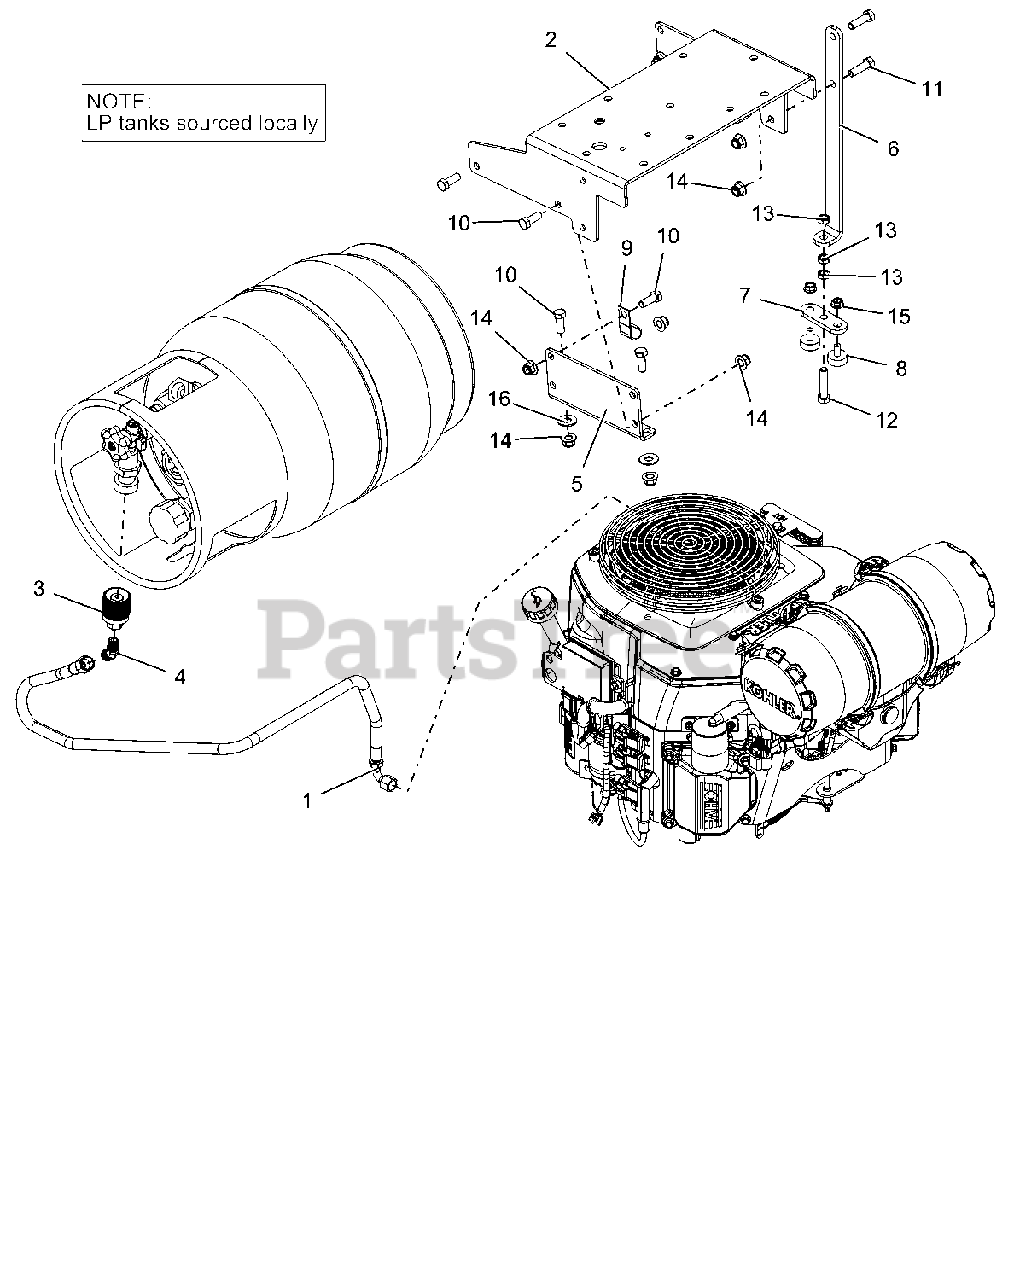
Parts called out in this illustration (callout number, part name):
1	HOSE, LPG SS25UL 6-4-6-30.00
2	SUPPORT, TANK
3	FTG, LPG TANK COUPLER -LH THRD
4	FTG, 45° 1/4-NPTF 9/16-18 45 FLG
5	MOUNT, TANK
6	STAND, TANK SIDE
7	BAR, FOOT
8	BUMPER, RUBBER
9	P-CLIP, .500 INSULATED
10	BLT-HEX .38-16X1.00 GR5 YWZC
11	BLT-HEX .38-16X1.25 GR5 YWZC
12	BLT-HEX .38-16X1.75 GR5 YWZC
13	NUT, JAM .375-16 YWZC
14	NUT-LK-NYL-FLG .38-16 YWZC
15	@NUT-SPNLK-FLG .312-18 YWZC
16	WSHR-FL-STL.438X1.00X.083 YWZC
